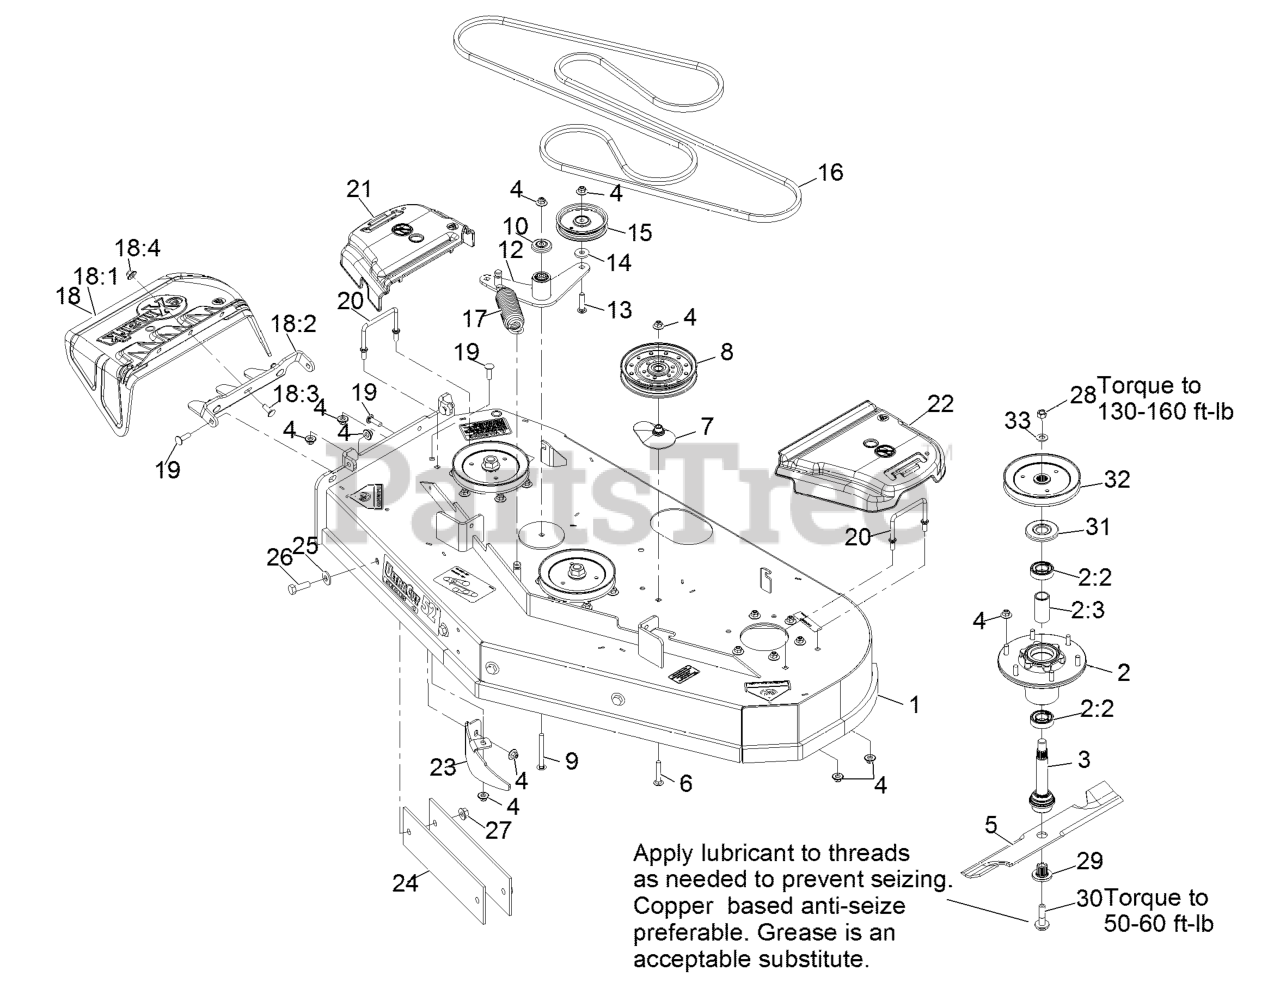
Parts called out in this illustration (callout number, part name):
1	DECK ASM-524
2	ASM-CUTTER HSG WITH BEARINGS
2:2	BEARING-BALL
2:3	SPACER-BEARING
3	ASM-SPINDLE AND SEAL
4	Nut-Nyloc 3/8-16 Flg
6	Bolt-Carriage 3/8-16 X 2 1/4
7	SPACER-PULLEY
9	SCREW-CARR
10	GUARD-TOP
12	IDLER ARM ASM W/BEARINGS
13	SCREW-CARR SPECIAL
15	PULLEY-IDLER
16	BELT-V
17	SPRING-EXTENSION
18	ASM,DISCHARGE CHUTE
18:1	CHUTE,DISCHARGE
18:2	BRACKET,DISCHARGE CHUTE
18:3	SCREW-CARR
18:4	Nut-Nyloc 3/8-16 Flg
19	Bolt-Carriage 3/8-16 X 1 1/4
20	WIREFORM-COVER
21	COVER-BELT, RH
22	COVER-BELT, LH
23	BAFFLE-DOGLEG, LZ-VT52
24	BAR,WEIGHT
25	WASHER-SPRING
26	SCREW-HH
27	NUT-HHF
28	NUT-HEX
29	BUSHING,SPLINED
30	SCREW,SEMS 1/2-20 X 2.19
31	GUARD,BEARING TOP .989
32	SHEAVE,BLADE DRIVE 6.50
